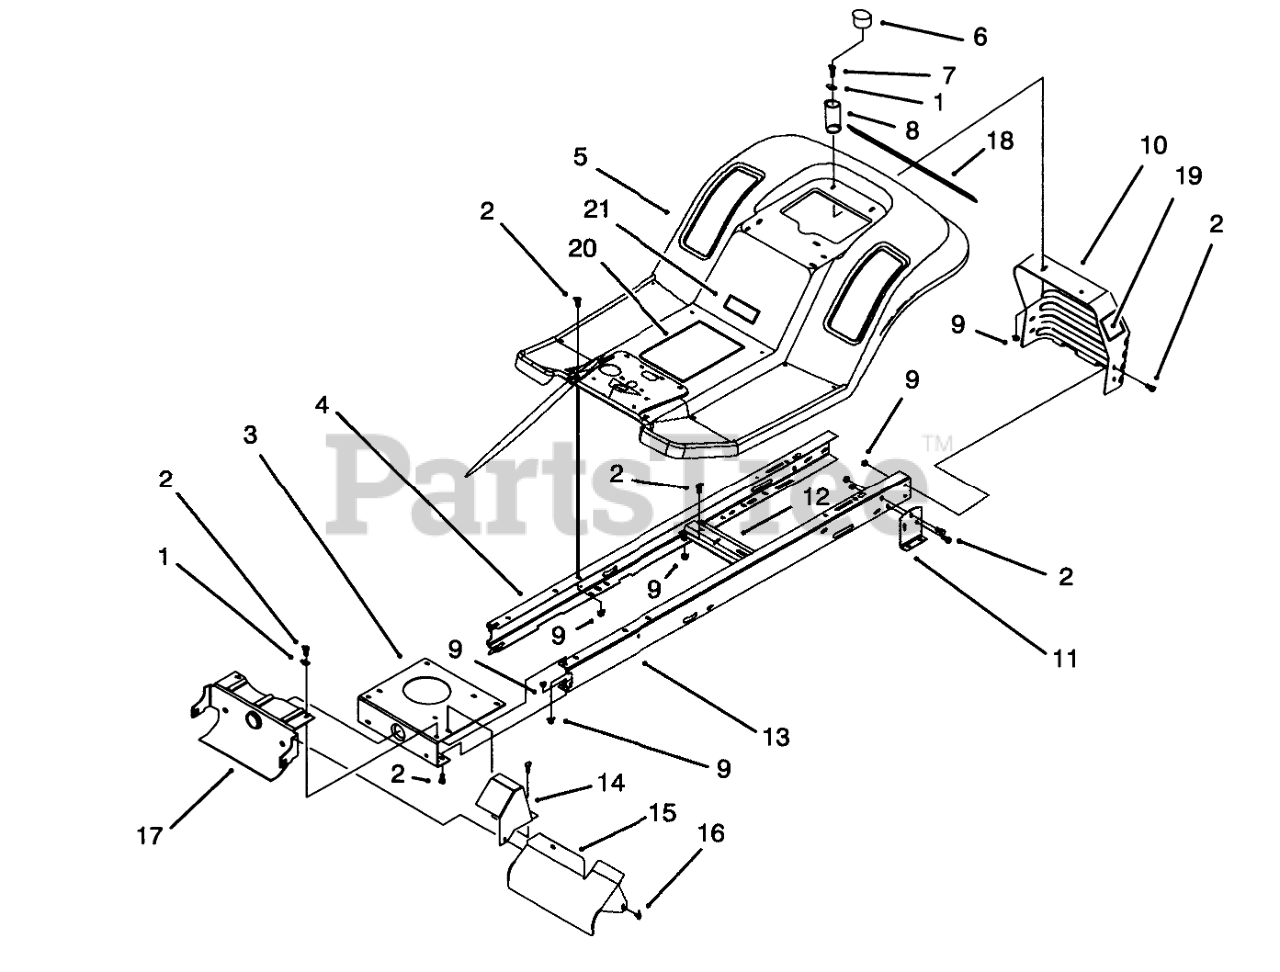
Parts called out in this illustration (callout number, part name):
1	WASHER-PLAIN
2	SCREW-HH
3	Plate-Engine Mount
4	Frame-Rail R.H.
5	BODY-REAR
6	CAP-PROTECTOR
7	SCREW-HH
8	SPRING-COMPRESSION
9	NUT-LOCK, NI
10	Panel-Rear Hitch
11	Bracket-Transaxle
12	Bracket-Idle Pivot
13	Frame-Rail L.H.
14	Shield-Exhaust Pipe
15	Shield-Muffler
16	SCREW-HWHTF
17	Support-FrontAxle
18	DECAL - REAR BODY
19	DECAL-DUMP VALVE
20	Decal-Instruction Hydro
21	Decal-Made In USA
